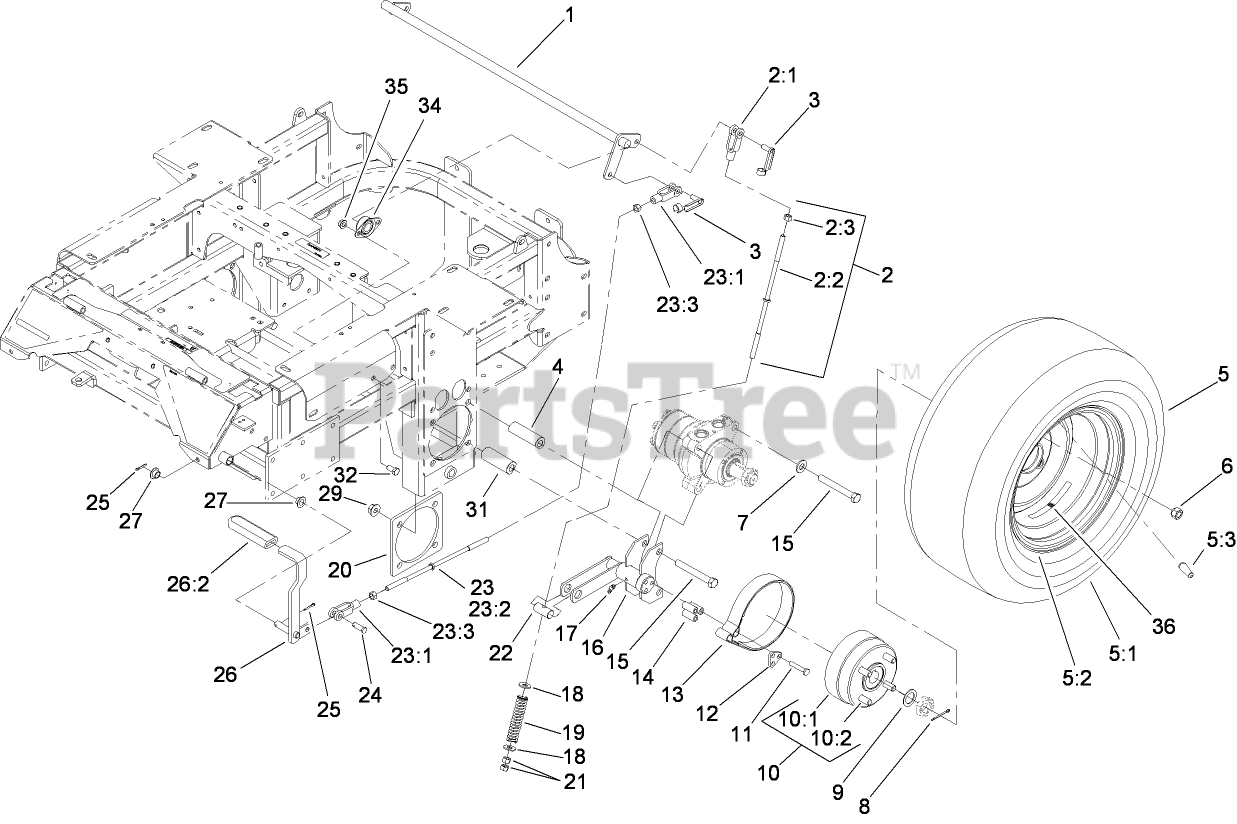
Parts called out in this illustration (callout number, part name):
1	SHAFT-BRAKE
2	BRAKE ROD ASM
2:1	YOKE-LINKAGE, BRAKE
2:2	ROD-BRAKE
2:3	NUT-HEX
3	Pin-Spring, Clevis
4	SPACER-WHEEL, LONG
5	WHEEL AND TIRE ASM
5:2	WHEEL RIM
5:3	STEM-VALVE
6	NUT-LUG
7	WASHER-THRUST
8	PIN-COTTER
9	WASHER-SPACER
10	WHEEL HUB ASM
10:1	HUB-WHEEL
10:2	STUD-WHEEL
11	SCREW-HH
12	RETAINER-BAND, BRAKE
13	BAND-BRAKE
14	SPACER
15	SCREW-HH
16	BRAKE BRACKET ASM
17	FITTING-GREASE
18	WASHER-FLAT
19	SPRING-BRAKE
20	PLATE-REINFORCEMENT
21	NUT-HEX
22	PIN-TRUNION
23	BRAKE ROD ASM
23:1	YOKE-LINKAGE, BRAKE
23:2	ROD-BRAKE
23:3	NUT-HEX
24	PIN-CLEVIS
25	PIN-COTTER
26	BRAKE LEVER ASM
26:2	GRIP-LEVER
27	BEARING-CONTROL
29	NUT-HHF
31	SPACER-WHEEL, SHORT
32	SCREW-HH
34	BEARING-FLANGE, SIDE
35	NUT-HHF, WHIZ
36	DECAL
